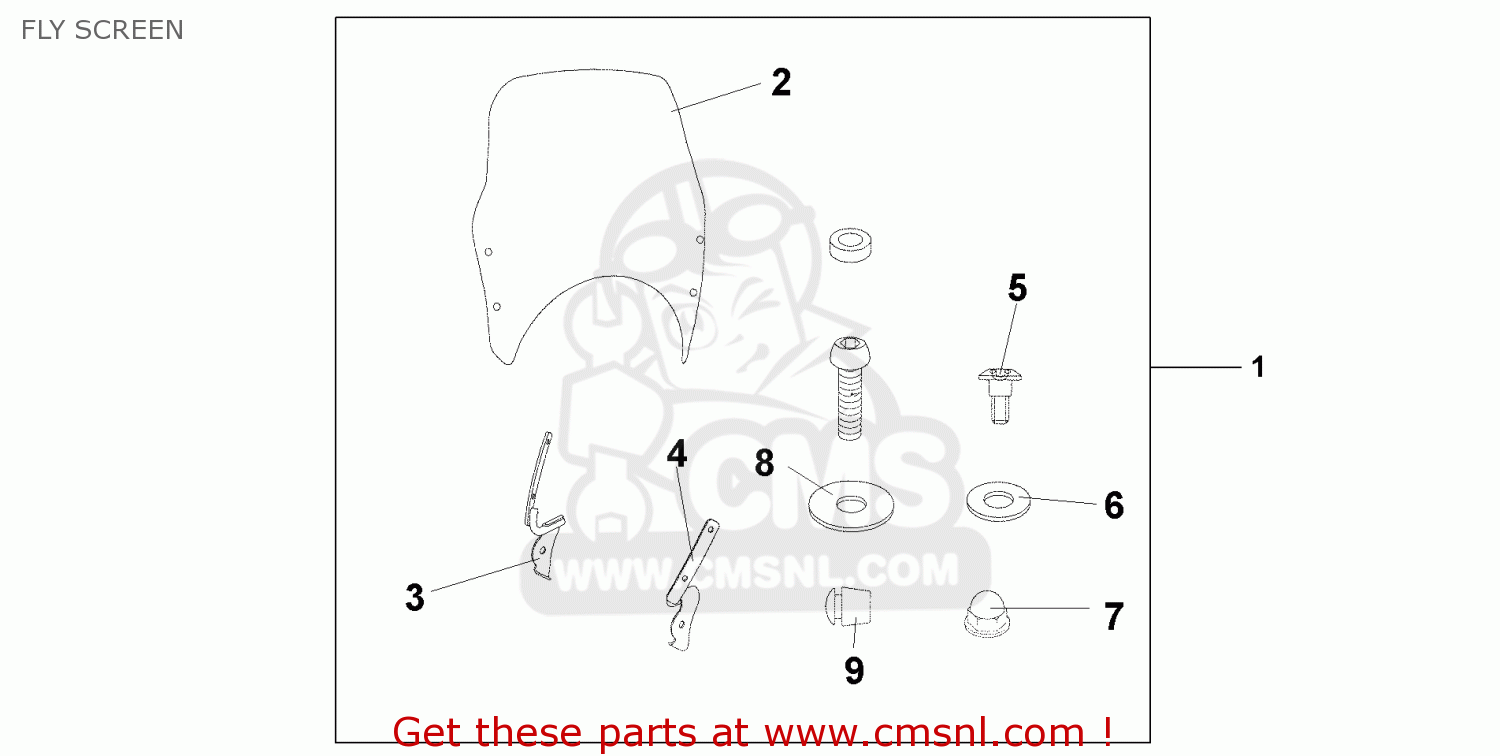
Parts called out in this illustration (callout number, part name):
1	FLY SCREEN
2	ASSY METER VISOR
3	STAY, RIGHT
4	STAY. LEFT
5	SCREW,PAN 6X14
6	WASHER C,8MM
7	NUT,CAP,6MM
8	RUBBER
9	RUBBER VISOR
